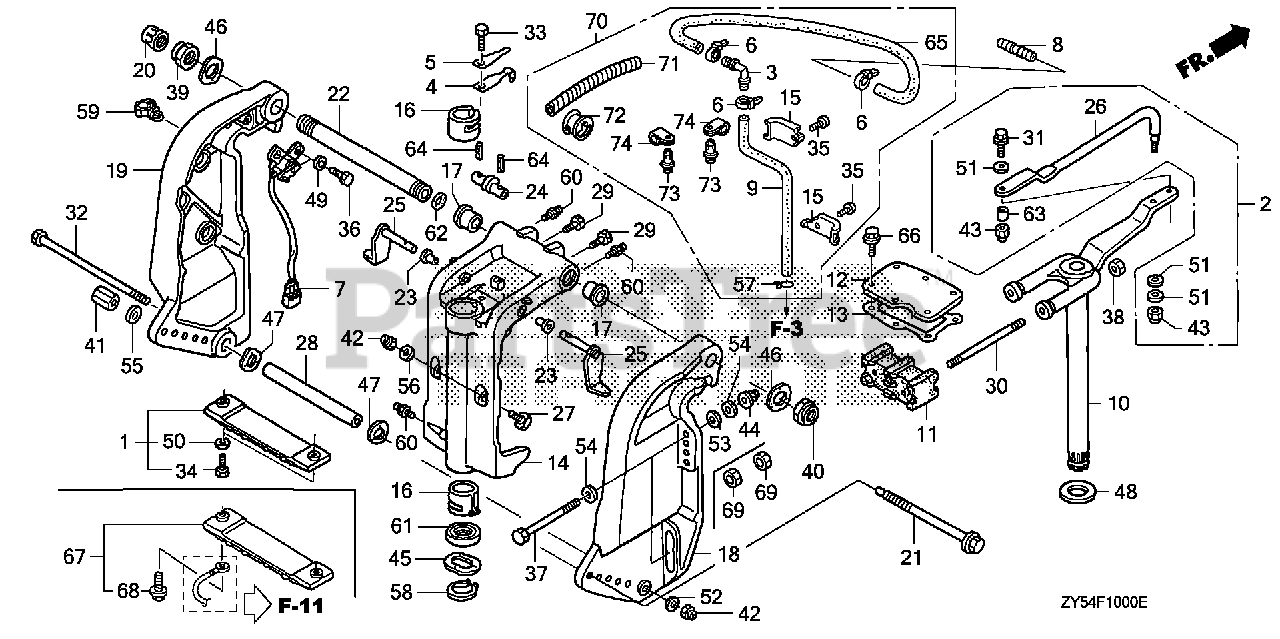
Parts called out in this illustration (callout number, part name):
2	ROD KIT, STEERING
3	JOINT A, BREATHER
4	SPRING, CLICK
5	SPRING, CLICK ASSIST
6	BAND, WIRE
7	SENSOR ASSY., TRIM ANGLE
8	END, NIPPLE
9	TUBE, SPEED SENSOR
10	FRAME, MOUNTING
11	MOUNT, RUBBER (UPPER)
12	HOLDER, MOUNTING (UPPER)
13	GASKET, MOUNTING HOLDER (UPPER)
14	CASE, SWIVEL *NH282MU* (OYSTER SILVER METALLIC-U)
15	PLATE, SPEED SENSOR TUBE
16	LINER, SWIVEL CASE
17	BUSH, SWIVEL CASE
18	BRACKET, R. STERN *NH282MU* (OYSTER SILVER METALLIC-U)
19	BRACKET, L. STERN *NH282MU* (OYSTER SILVER METALLIC-U)
20	CAP, TILTING BOLT
21	ROD, ADJUSTING
22	SHAFT, TILTING
23	BUSH, TILT ARM
24	BRACKET, TILTING
25	STOPPER, TILT
26	ROD, STEERING
27	RECEIVER, THRUST
28	COLLAR, CYLINDER (LOWER)
29	BOLT (1/4-28UNF)
30	BOLT, STUD (12X145)
31	BOLT (3/8-24UNF)
32	BOLT, HEX. (10X235)
33	BOLT, HEX. (6X14)
35	SCREW, PAN (6X8)
36	BOLT, FLANGE (6X20) (ENGINE NO.)
37	BOLT, HEX. (12X119)
38	NUT, FLANGE (12MM)
39	NUT, SELF-LOCK (7/8-14UNF)
40	NUT, SELF-LOCK (M25X2.0)
41	NUT, ADJUSTER ROD
42	NUT, SELF-LOCK (10MM)
42	NUT, FLANGE (10MM)
43	NUT, SELF-LOCK (3/8-24UNF)
44	NUT, SELF-LOCK (12MM)
45	WASHER, WAVE (40MM)
46	WASHER, WAVE (26MM)
48	WASHER, THRUST (34MM)
51	WASHER (10MM)
52	WASHER, PLAIN (10MM)
53	WASHER, PLAIN (12MM)
54	WASHER, PLAIN (12MM)
55	WASHER, PLAIN (12MM)
56	WASHER, PLAIN (10MM)
57	CLIP, TUBE (B8)
58	CIRCLIP (OUTER) (39MM)
59	CLIP, WIRE HARNESS
60	NIPPLE, GREASE
61	OIL SEAL (39.5X52X6) (ARAI)
62	O-RING (15.54X2.26)
63	COLLAR, STEERING ROD
64	PIN, SPRING (2.5X20)
65	BULK HOSE, VACUUM (5X3000) (5X250)
66	BOLT, FLANGE (8X35)
67	METAL KIT, ANODE Use from Frame SN 4800343.
68	BOLT, FLANGE (6X23) Use from Frame SN 4800343.
69	NUT, HEX. (12MM)
70	TUBE KIT, SPEED SENSOR
71	TUBE, SPIRAL
72	BUSH, MOTOR CODE
73	SCREW, RIVET (5X10)
74	CLIP (14MM)
74	CLIP (10.7MM)
